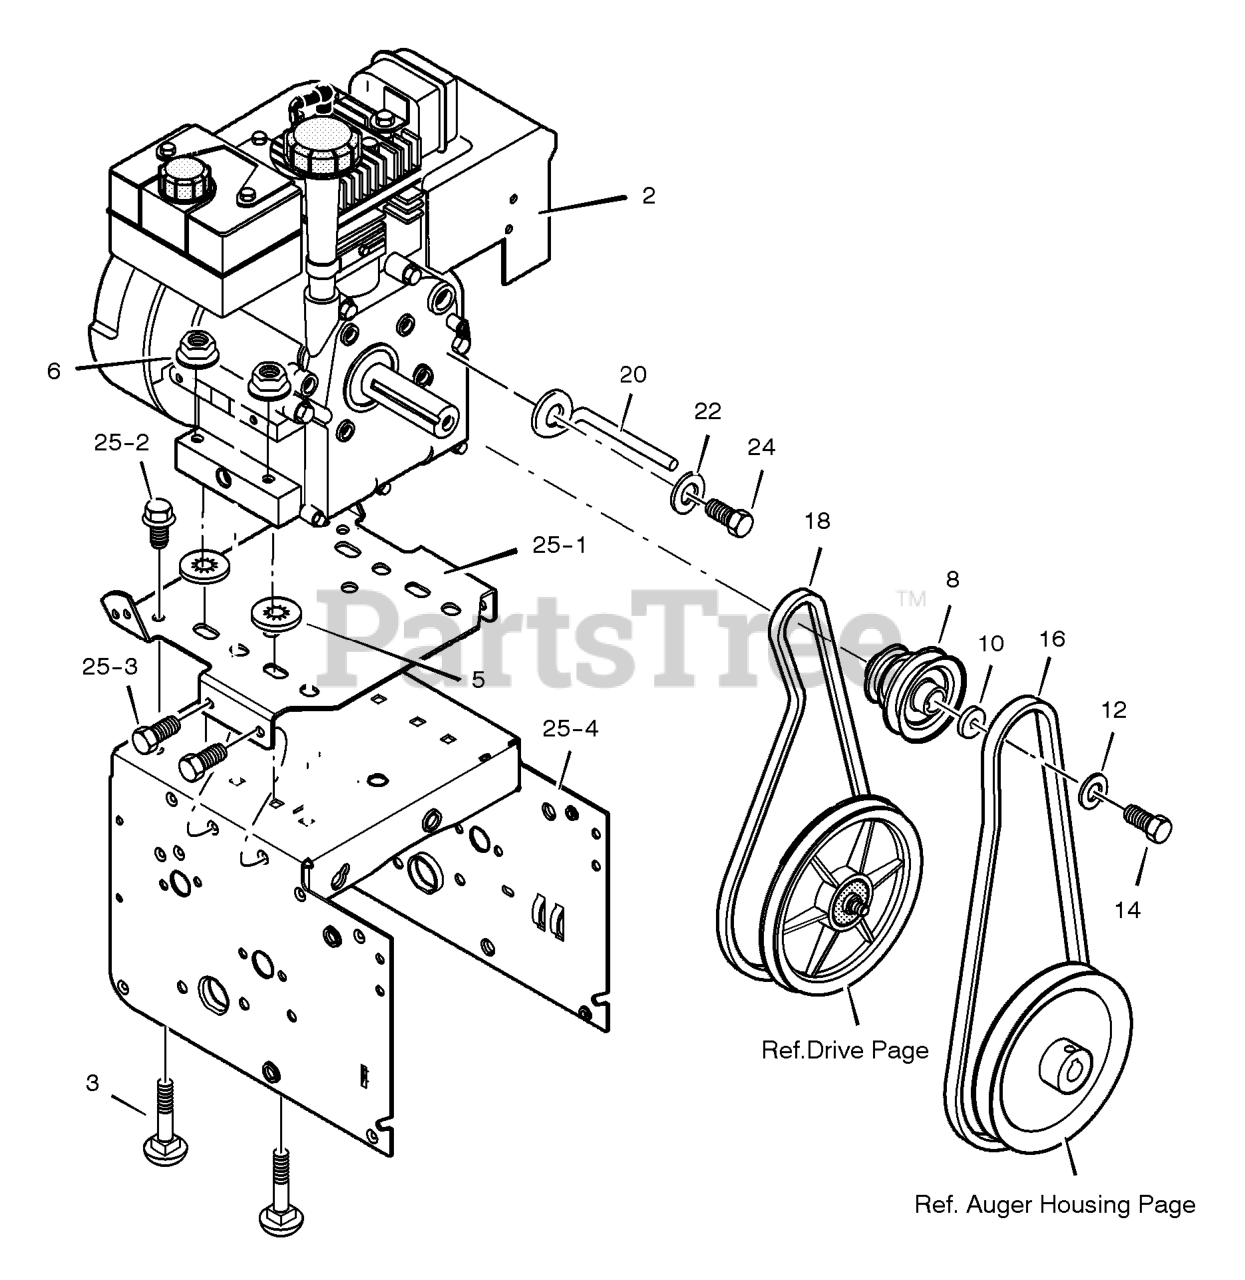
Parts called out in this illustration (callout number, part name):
2	ENGINE
3	BOLT, CARRIAGE 5/16-18
5	RETAINER, PUSH
6	NUT, HEXWDFLLK 5/16-18
8	PULLEY, ENGINE
10	WASHER
12	WASHER .38ID
14	SCREW, 3/8-24 x 1.00
16	BELT, V 4L35.6 LG
18	BELT, V 3L 33.13LG
20	GUIDE, BELT
22	WASHER, SPTLK .31X.58X.08
24	SCREW, 5/16-24 x 0.75
25	FRAME, MOTORBOX
25-1	PLATE, ENGINE MOUNT
25-2	SCREW, TAP 1/4-20 X .63
25-3	SCREW, TAP 5/16-18 X .50
25-4	FRAME, MOTOR BOX
